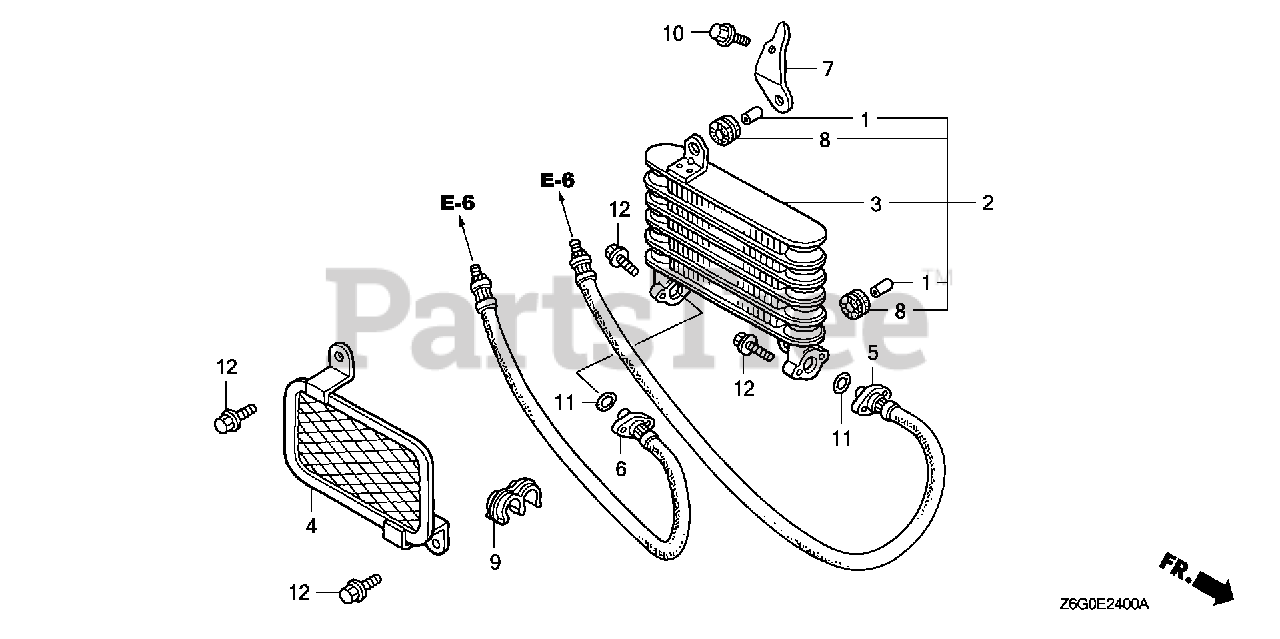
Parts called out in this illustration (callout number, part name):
1	COLLAR (12MM)
2	COOLER ASSY., OIL
3	COOLER, OIL
4	GRILLE, OIL COOLER
5	HOSE A, OIL
6	HOSE B, OIL
7	STAY, OIL COOLER
8	RUBBER, RADIATOR MOUNTING
9	CLAMP, HOSE (D13.5)
10	BOLT, FLANGE (6X14)
11	O-RING (10X2.6) (ARAI)
12	BOLT, FLANGE (6X22)
